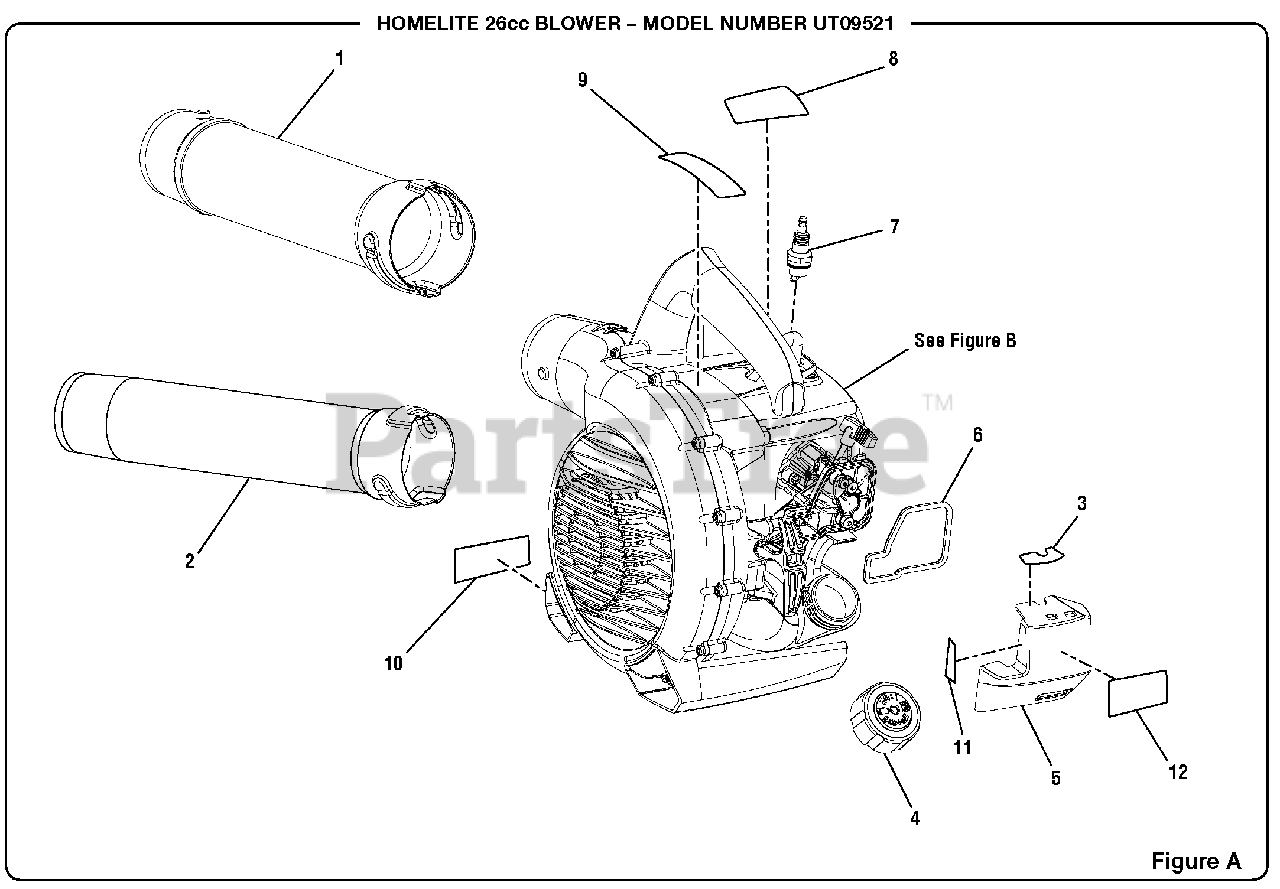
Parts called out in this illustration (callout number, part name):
1	Upper Blower Tube
2	Sweeper Nozzle
3	Throttle Label
4	Fuel Cap Assembly
5	Air Box Cover
6	Air Box Gasket
7	Spark Plug (RCJ6Y)
8	Model Label
9	Warning Label
10	Combustion Warning Label
11	Choke Label
12	Starting Instructions Label
